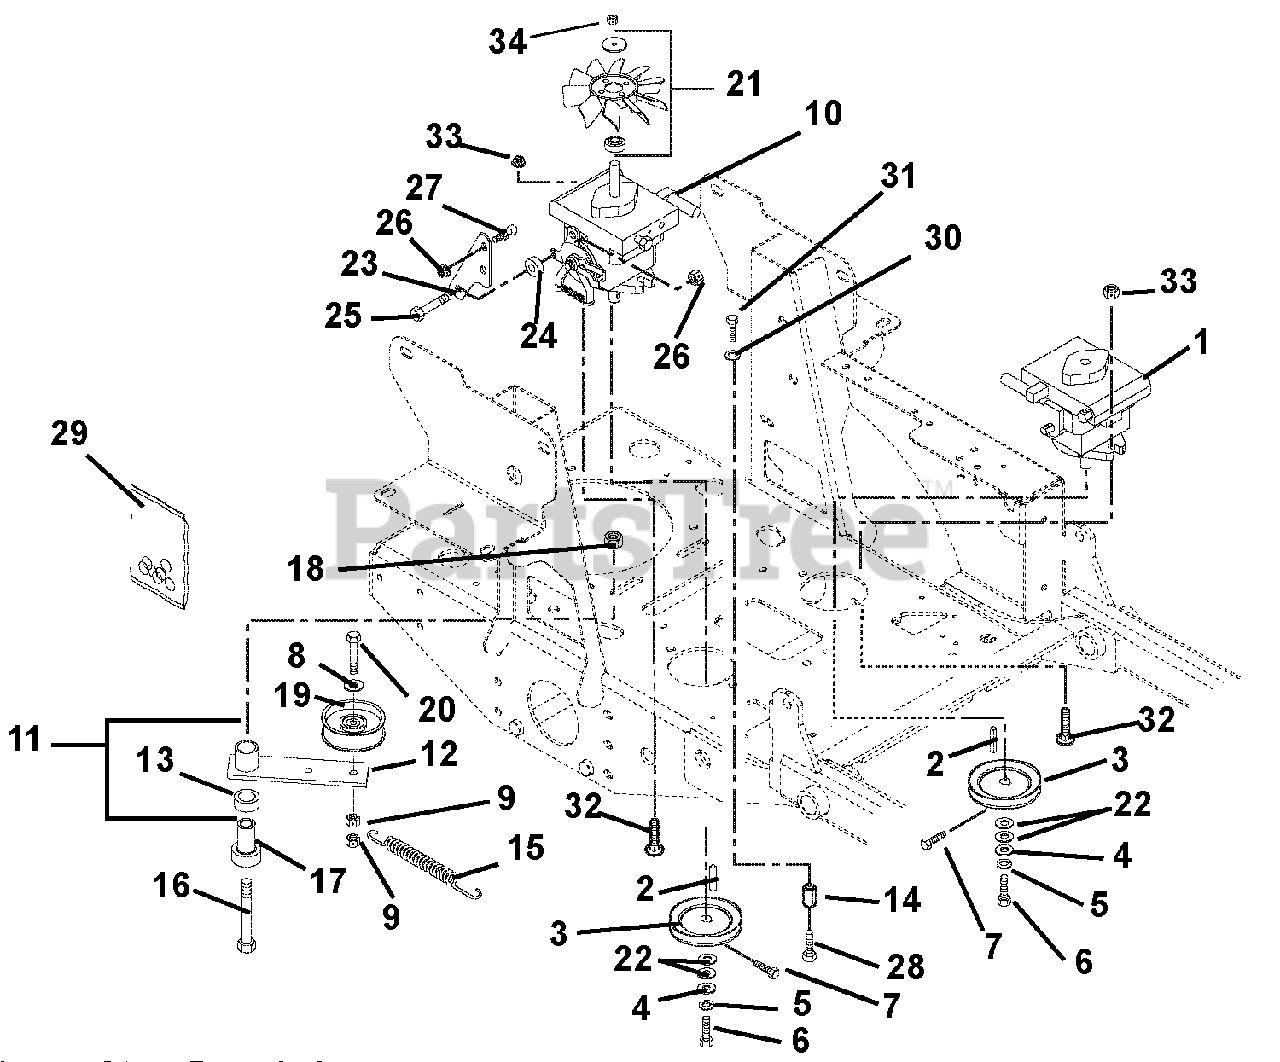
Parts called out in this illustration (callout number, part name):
1	PUMP, HYD BDP-10A (LH)
2	KEY-STR 5MMX25MMX5MM
3	SHEAVE, PUMP .592 X 4.345
4	WSHR-FL-STL .281X1.000X.063
5	@WSHR-LK .25X.062 REG YWZC
6	BLT-HEX M6 X 1.0X12 YWZC
7	BLT-HEX .25-20X.50 GR5 EPOXY
8	WSHR-FL-STL .390X.75X.125 YWZC
9	@NUT-LK-NYL-FLG .38-16 YWZC
10	PUMP, BDP-10A-441 (THRU SHAFT)
11	ASSEMBLY,IDLER ARM GRD.DRIVE
12	WMT, IDLER ARM GROUND DRIVE
13	BRG, 1.00 X 1.12 X .75
14	NUT COUPLING .375-16X1.75
15	SPRING, EXTENSION
16	@BLT-HEX .50-13X3.50 GR5 YWZC
17	BEARING, PEDESTAL
18	@NUT-LK-NYL-FLG .50-13 YWZC
19	IDLER, FLAT 4.00X1.06
20	@BLT-HEX .38-16X2.25 GR5 YWZC
21	FAN, COOLING (W/ HUB & WASHER)
22	@WSHR-FL-STL.656X1.31X.095 YWZ
23	BRACKET, RTN/DAMPER
24	SPACER .344X1.000X.375
25	@BLT-HEX .31-18X1.25 GR5 YWZC
26	@NUT-LK-NYL-FLG .31-18 YWZC
27	STUD- BALL
28	@BLT-HEX .38-16X1.50 GR5 YWZC
29	KIT, PUMP SEAL
30	@WSHR-LK .38X.094 REG YWZC
31	@BLT-HEX .38-16X.75 GR5 YWZC
32	@BLT-RDHDSQNK .44-14X1.50 G5YZ
33	NUT-LK-NYL-FLG .44-14 YWZC
34	NUT-CTRLK .31-24 YWZC
